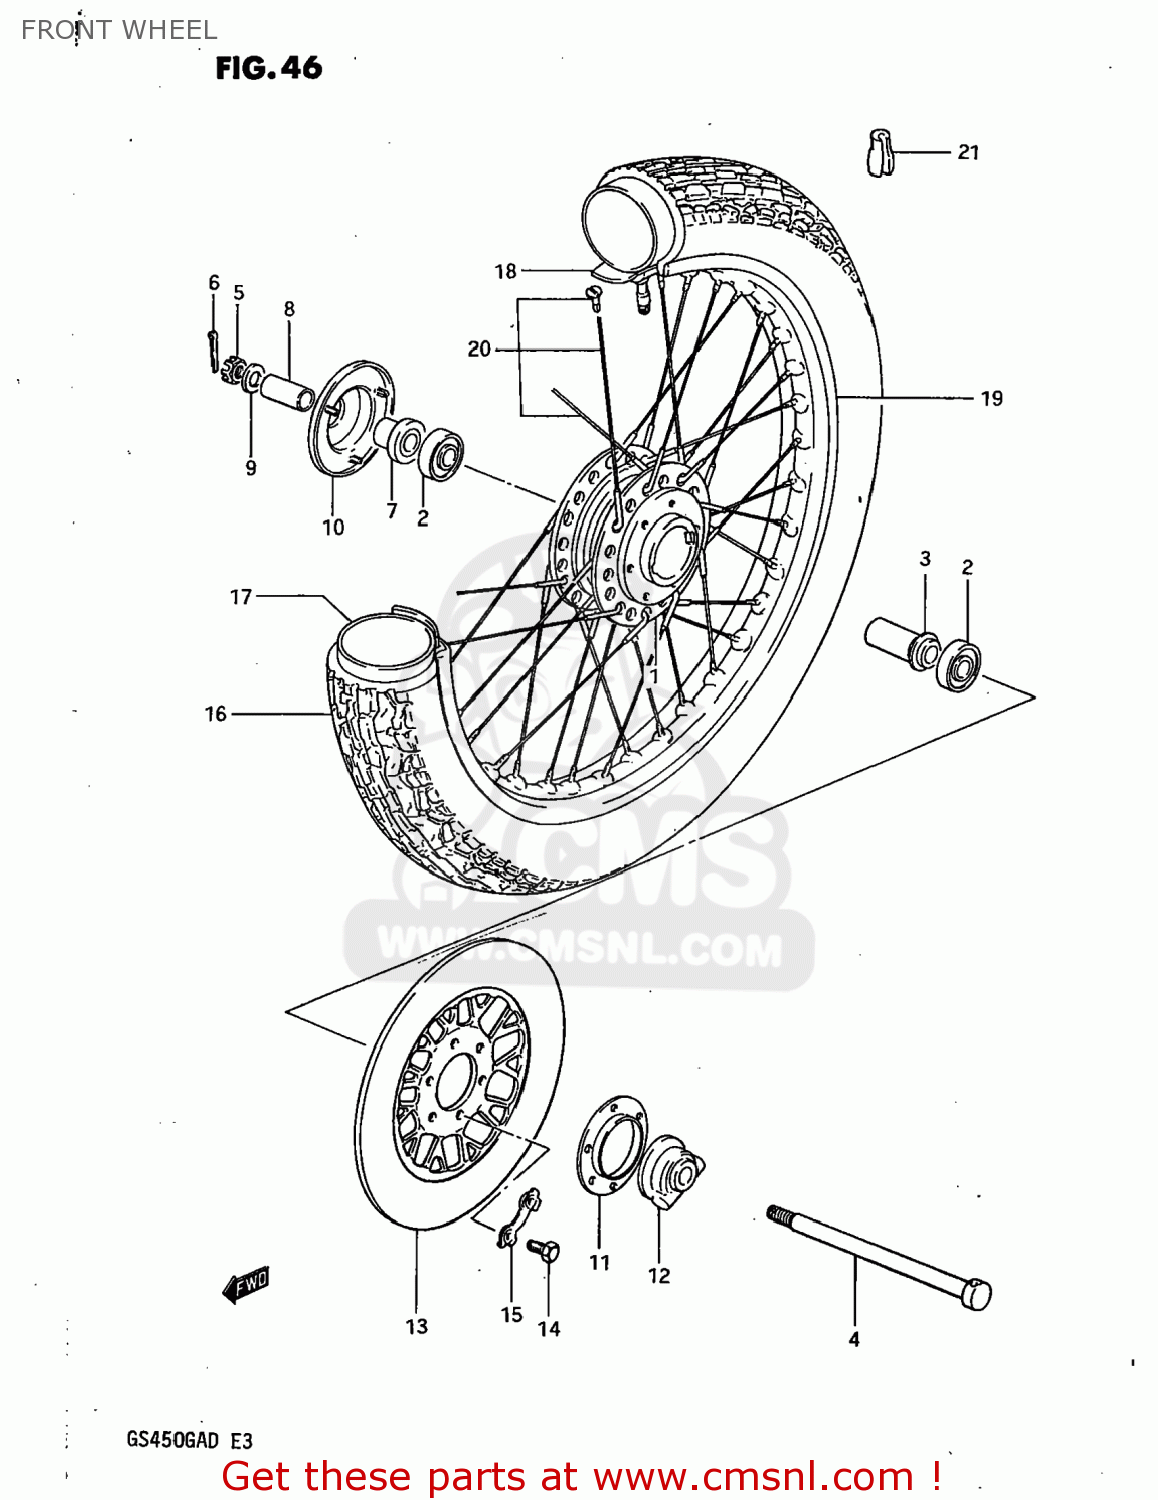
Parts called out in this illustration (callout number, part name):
1	DRUM,FRONT HUB
2	BEARING
3	SPACER,FR HUB BEARING
4	AXLE,FRONT
5	NUT 12MM
6	COTTER PIN
7	SPACER,FR HUB BEARING,R
8	SPACER(15X22X30)
9	WASHER
10	COVER,FR HUB,R
11	DUST SEAL,SPEEDOMETER GEAR BOX
12	BOX ASSY,SPEEDOMETER GEAR
13	DISC,FR BRAKE
14	BOLT(8X25)
15	WASHER
16	TIRE
17	TUBE,INNER
18	PROTECTOR,INNER TUBE
19	RIM,FRONT WHEEL
20	SPOKE ASSY,FR WHEEL
21	BALANCER,WHEEL (B)
